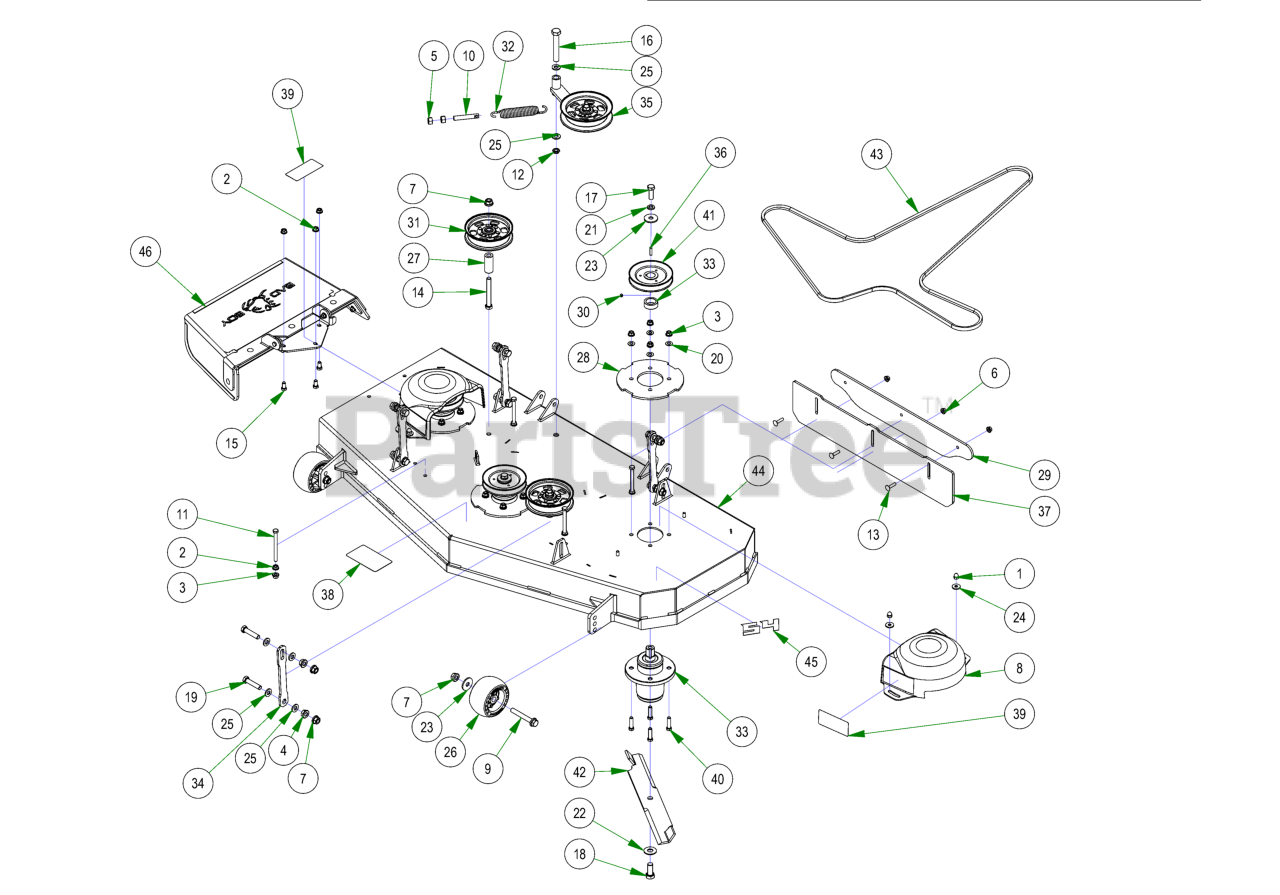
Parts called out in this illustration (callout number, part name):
1	5/16-18 ACORN NUT HIGH-CROWN ZC
2	3/8-16 HEX SERRATED FLANGE NUT HARD/ZINC
3	3/8-16 NYLON INSERT FLANGE LOCKNUT (GR.F) ZINC
4	1/2-13 HEX SERRATED FLANGE NUT HARD/ZINC
5	1/2-13 HEX NUT ZINC
6	5/16-18 NYLON INSERT FLANGE LOCKNUT ZINC
7	1/2-13 NYLON INSERT FLANGE LOCKNUT ZINC
8	Pulley Cover
9	1/2-13 X 90MM HEX FLANGE BOLT W/SHOULDER (GR.8) ZINC
10	All Thread
11	3/8-16 X 4-1/4 HEX CAP SCREW (GR.5) ZINC
12	1/2-13 NYLON INSERT JAM LOCKNUT ZINC
13	5/16-18 X 1-1/4 CARRIAGE BOLT ZINC
14	1/2-13 X 4 HEX CAP SCREW (GR.8) ZINC YELLOW
15	3/8-16 X 3/4 HEX CAP SCREW (GR.5) ZINC
16	5/8-11 X 4 HEX CAP SCREW (GR.8) ZINC YELLOW
17	1/2"-20 x 1 1/2 - Grade 5 Fine Thread Bolt
18	5/8-18 X 1-1/2 HEX CAP SCREW (GR.8) ZINC YELLOW
19	1/2-13 X 2-1/4 HEX CAP SCREW (GR.5) ZINC
20	3/8 F/W SAE (13/16 OD) ZINC
21	1/2 SPLIT LOCKWASHER (GR.8) ZINC/YELLOW
22	5/8 USS FLAT WASHER (1-3/4" OD) GR.8 ZINC YELLOW
23	1/2 BELLEVILLE WASHER (1-5/8 OD X .140 THK) ZINC
24	.360 ID X .983 OD X .120 THICK FLAT WASHER NYLON BLACK
25	.505 ID X 1.000 OD X .125 THICK FLAT WASHER NYLON
26	Deck Wheel
27	2019 Revolt Stationary Idle Spacer
28	Deck Spindle Support Plate
29	Striping Kit Plate
30	5/16-24 X 1/4 SOCKET SET SCREW (CUP PT) PLAIN
31	5-3/4 Idler Pulley
32	Deck Idler Spring
33	OUTLAW SPINDLE ASSEMBLY
34	23WB Deck Hanger
35	2019 Revolt Deck Idler Assembly
36	1/4 X 1 SQ MACHINERY KEY 1018 STL PLN
37	2023 MZ Stripping Kit Rubber
38	2017 MZ Magnum 48"/42" Deck Route Decal
39	Danger Decal-Spindle/Discharge
40	3/8-16 X 1-1/2 HEX CAP SCREW (GR.5) ZINC
41	5.25" Deck Spindle Pulley
42	54" Fusion Blade for Avenger/ZT/Mav/Outlaw/Revolt
43	B128 Deck Belt
44	23WB 54in Deck
45	54" Deck Decal
46	Discharge Chute Assembly
